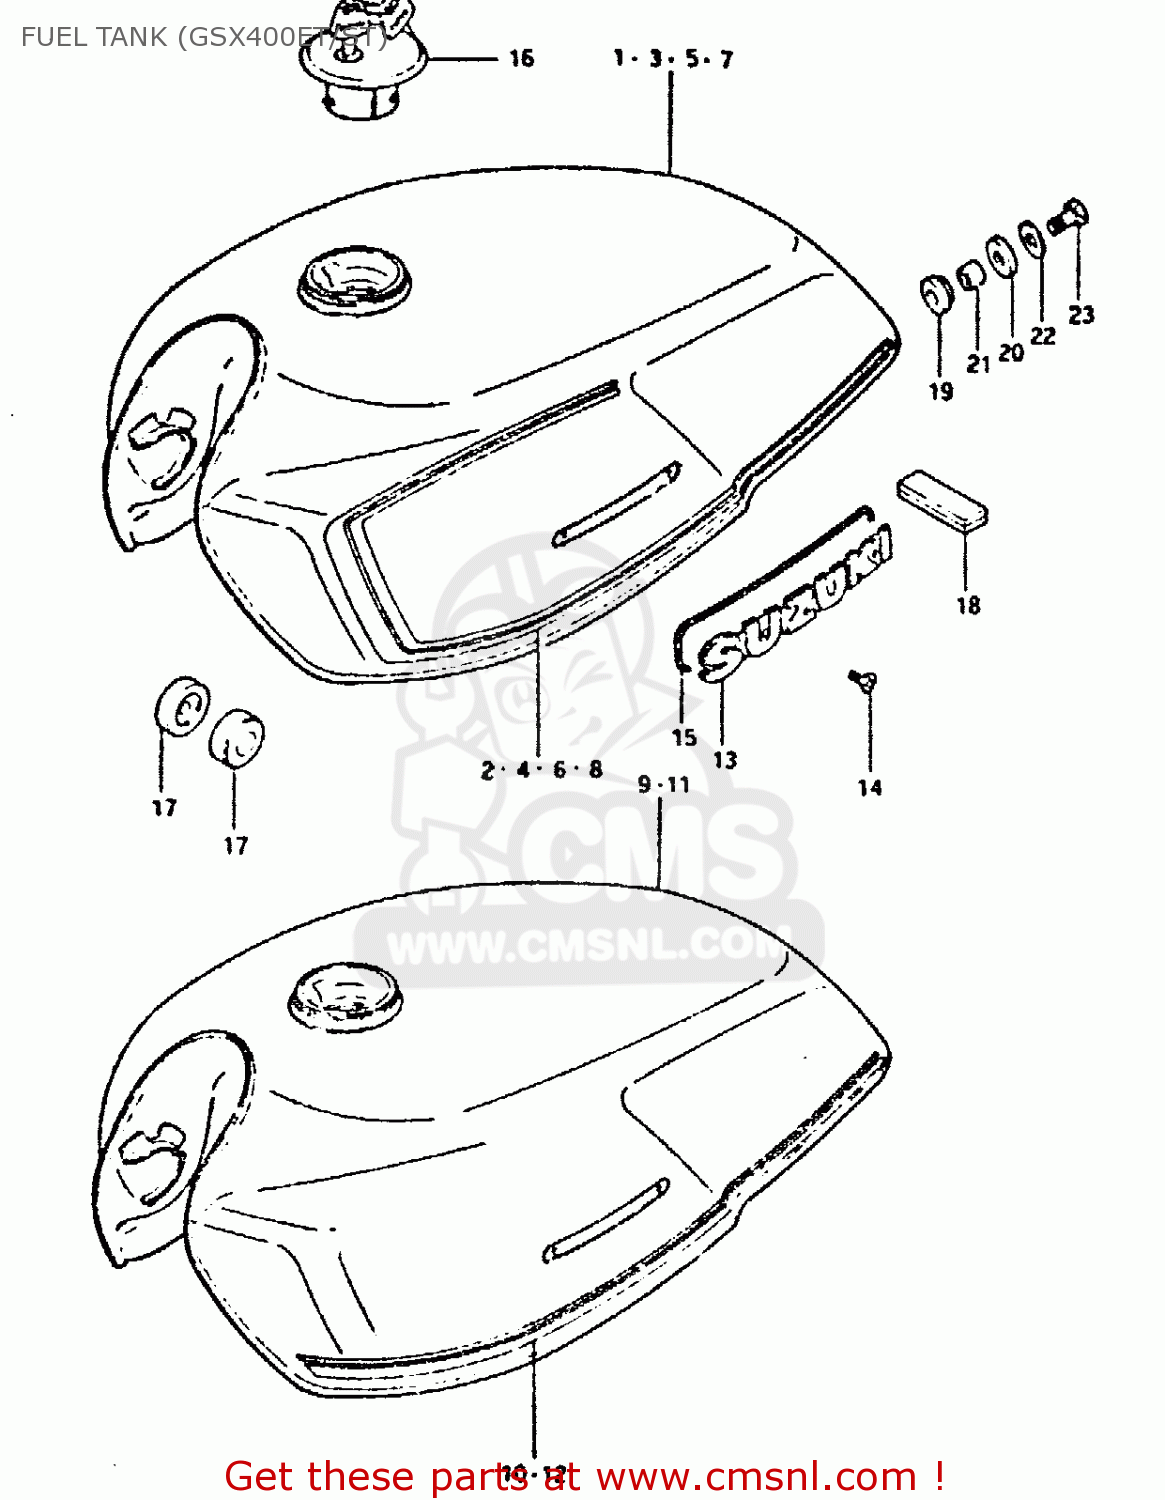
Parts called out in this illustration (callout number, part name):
1	TANK, FUEL (BLACK)
2	TAPE SET
3	TANK, FUEL (BLUE)
4	TAPE SET
5	TANK, FUEL (RED)
6	TAPE SET
7	TANK, FUEL (SILVER)
8	TAPE SET
9	TANK, FUEL (BLACK)
10	TAPE SET
11	TANK, FUEL (SILVER)
12	TAPE SET
13	EMBLEM
14	SCREW 3X6
16	CAP SET,FUEL TANK
17	CUSHION
18	CUSHION
19	CUSHION
20	CUSHION
21	SPACER(8.5X12X19)
22	WASHER (8.5X29X1.6)
23	BOLT (8X30)
